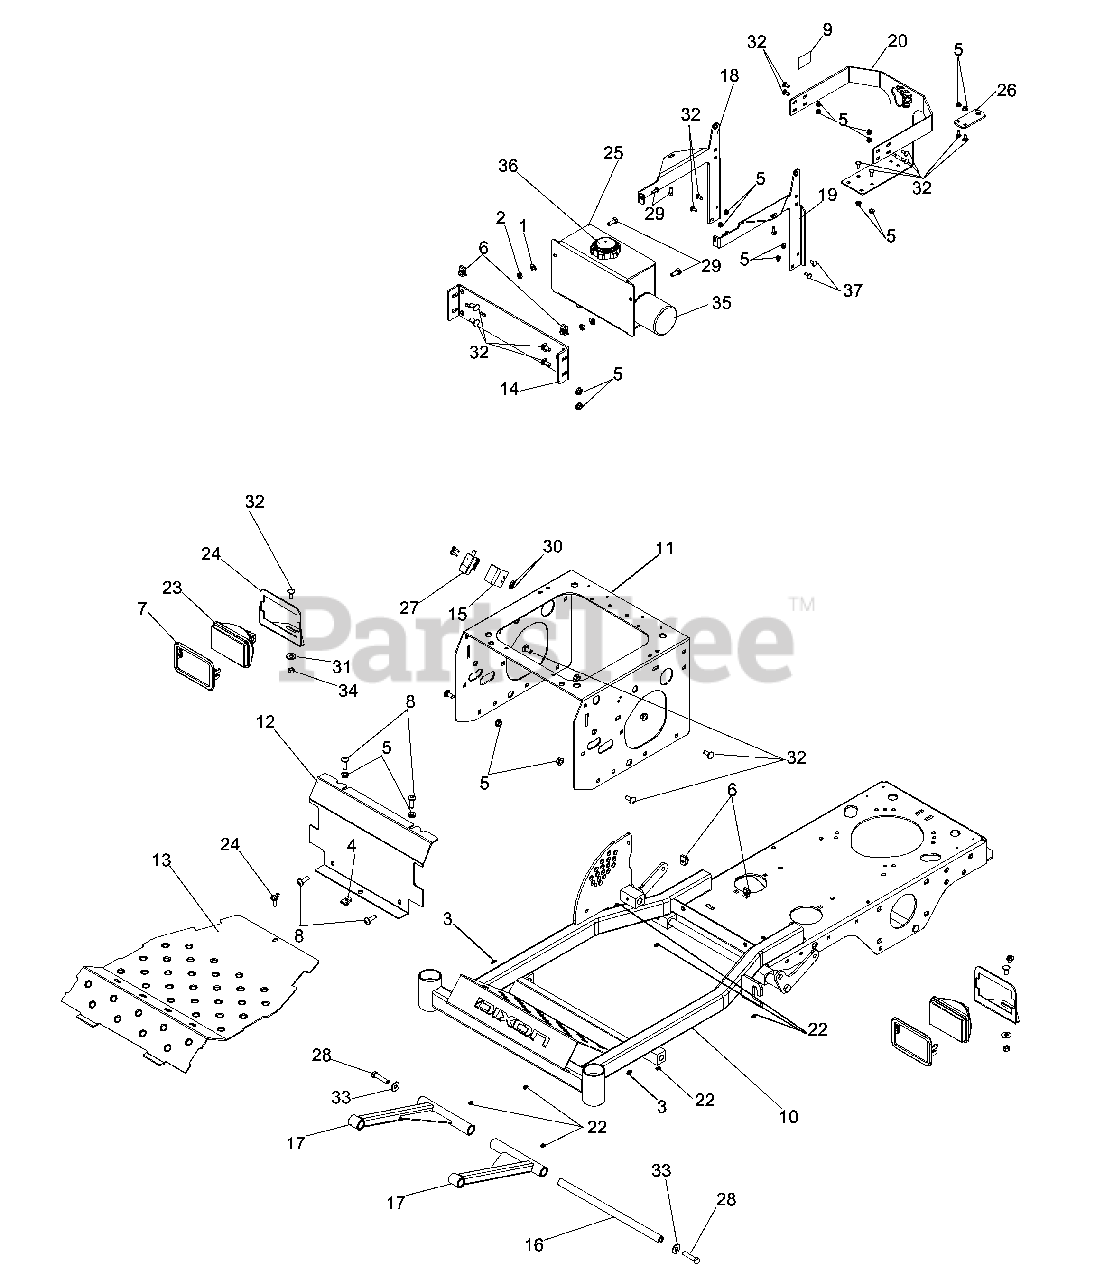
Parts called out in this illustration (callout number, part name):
1	5/16STD FL WASH TYPA
2	5/16-18 THIN PROF NY
3	ZERK, 3/16, DRIVE IN
4	1/4-20 U NUT
5	5/16-18 FLANGED L-NUT
6	CLIP NUT 5/16-18
7	HEADLIGHT BEZEL
8	5/16-18X1 FLANGED SCREW
9	DECAL, PARKER
10	FRAME WLDT. B/B
11	CHANNEL SEAT MT.
12	FRONT PANEL
13	FOOT PLATE
14	CHANNEL HYD TANK MT.
15	MT. SWITCH
16	SPACER FRAME
17	TRAILING ARM WLDT.
18	FENDER SUPPORT
19	TANK SUPPORT KAW
20	REAR GUARD KAW
21	1/4-20 X 3/4 WING BOLT
22	GREASE ZERK-1/4"
23	HEADLIGHT
24	BRACKET HEADLIGHT.
25	TANK ASM W/FILTER & CAP
27	BRAKE SWITCH
28	CAPSCREW HX3/8-24X1-3/4
29	HCS 5/16C X 3/4
30	NUT 10-24 NYLOC
31	FLAT WASHER 5/16 SAE
33	WASHER 3/8 FLAT
34	NUT 5/16 NYLOC
35	HYDRAULIC OIL FILTER
36	HYDRO TANK CAP-KELCH
